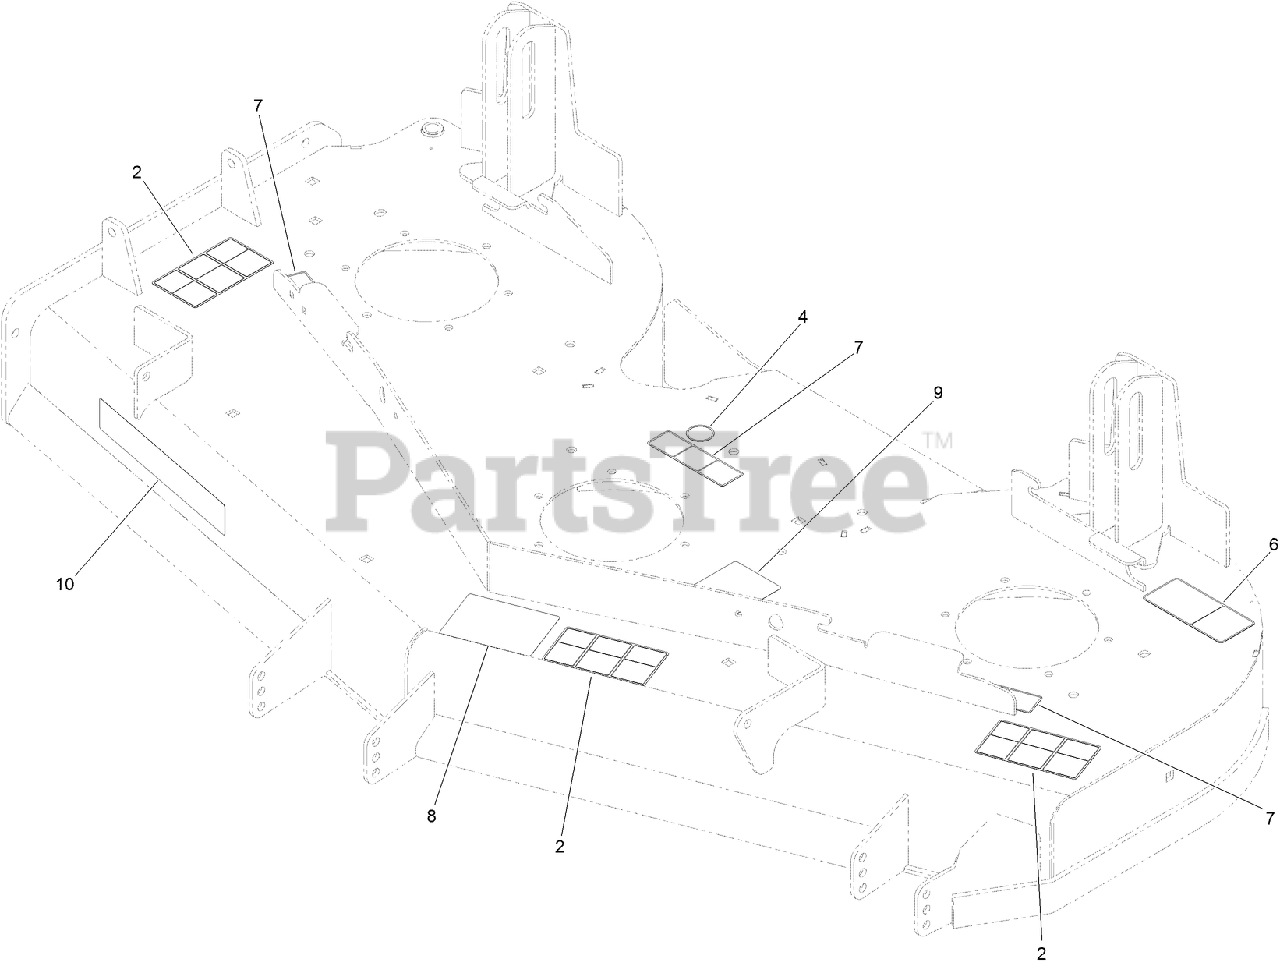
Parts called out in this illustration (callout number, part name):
2	DECAL-DANGER
4	DECAL-GREASE
6	DECAL-TORQUE, BLADE BOLT
7	DECAL-MISSING, COVER
8	DECAL-SCALP, ANTI
9	DECAL-ROUTING, DECK BELT
